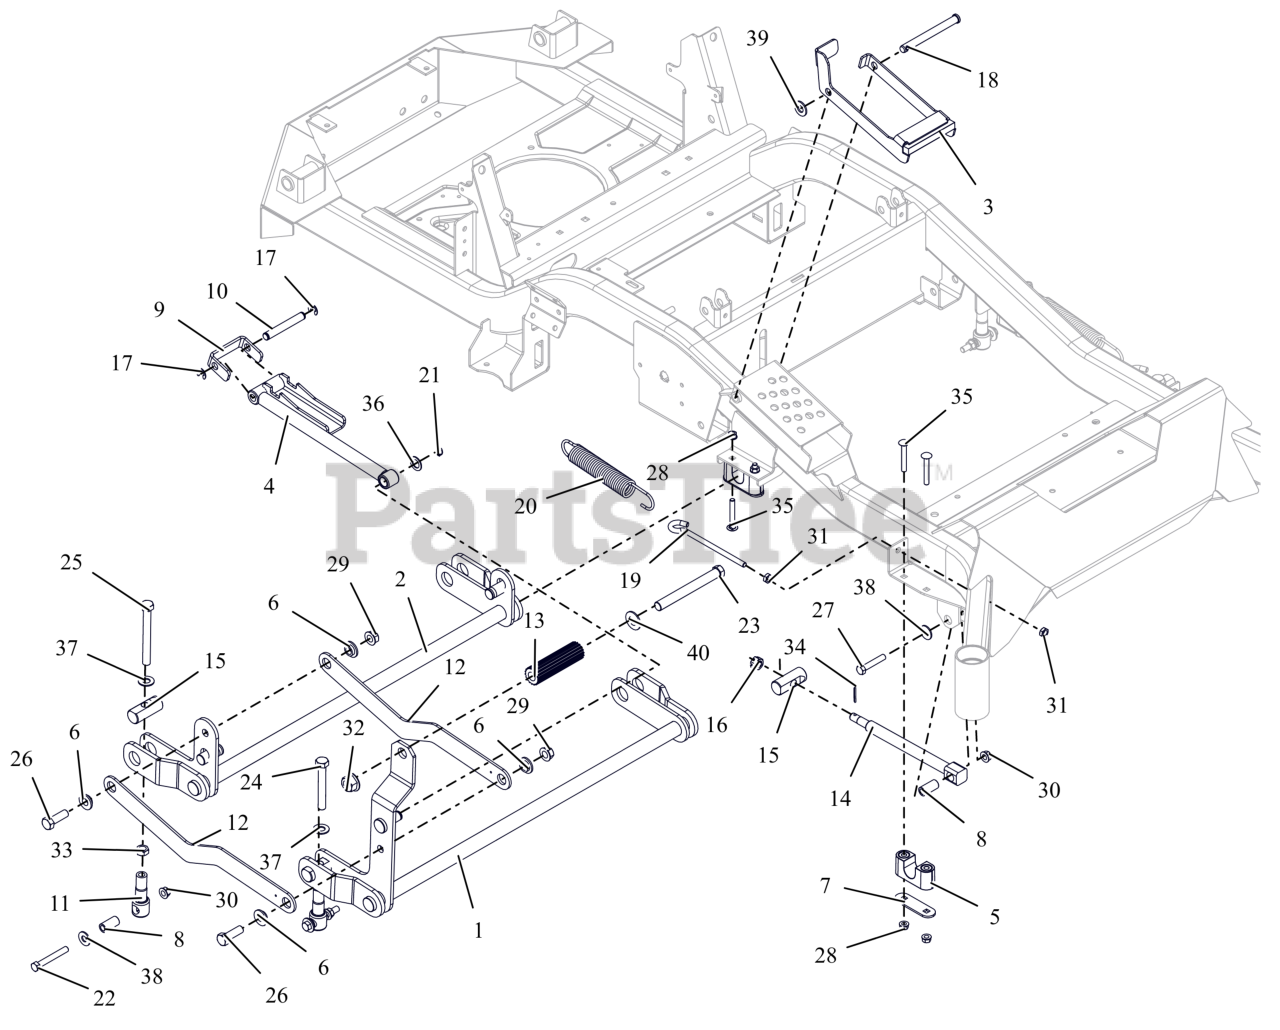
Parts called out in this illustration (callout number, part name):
1	WLDMT, FRONT DECK LIFT PIVOT
2	WLDMT, REAR DECK LIFT PIVOT
3	BRKT, HOC TRANSFER LOCK
4	WLDMT, HOC ARM
5	ASM-BUSHING, DECK LIFT
6	BSHG-FLG .515X.750X.395X1.120
7	PLATE, BEARING SUPPORT
8	SPACER, DECK LEVELING
9	BRKT, HOC LINE
10	ROD, HOC PIVOT
11	LINK, DECK LIFT FORMED
12	LINK, DECK LIFT
13	ROD, FOOT PEDAL (BLACK)
14	DRAG,LINK-HD
15	PIN, DECK LIFT
16	NUT-SL .50-13
17	RG-RTNG-EXT .500X.042 (E)
18	PIN-SLIC .50X4.97X4.55 -ZCC
19	BOLT,.38-16 X 5.25-.62 DIA EYE
20	SG-TENS .162X1.25X8.25 WLD 25
21	RG-RTNG-EXT .625X.050
22	BLT, HEX .38-16X2.75 G8 ZCC
23	BLT, HEX .62-11X5.50 G5 FBP
24	BLT, HEX .50-13X3.50F G5 ZCC
25	BLT, HEX .50-13X4.50F G8 ZCC
26	BLT,HEX .50-13X1.50 G5 ZCC
27	BLT,HEX .38-16X2.00 G5 ZCC
28	NUT,LK-CTR-FLG .31-18 GF ZCC
29	NUT-LK-TOP-FLG .500-13 GF ZCC
30	NUT-LK-TOP-FLG .38-16 ZC120
31	NUT-JAM .375-16 G2 ZCC
32	NUT,FLG-TOP LK .625-11 FBP
33	NUT-JAM .500-13 G2 ZCC
34	PIN,CTR.12X1.25EXTPRSQCT ZC120
35	BLT, RHSSN.31-18X2.25 G5 ZCC
36	WSHR, FLT .630X1.005X.062 ZCC
37	WSHR, FLT .557X1.040X.102 ZCC
38	WSHR,FLT .438X1.00X.083 ZCC
39	WSHR,FLT .531X1.062X.095 ZCC
40	WSHRFLT 5/8SAE CARBHARD FBP
